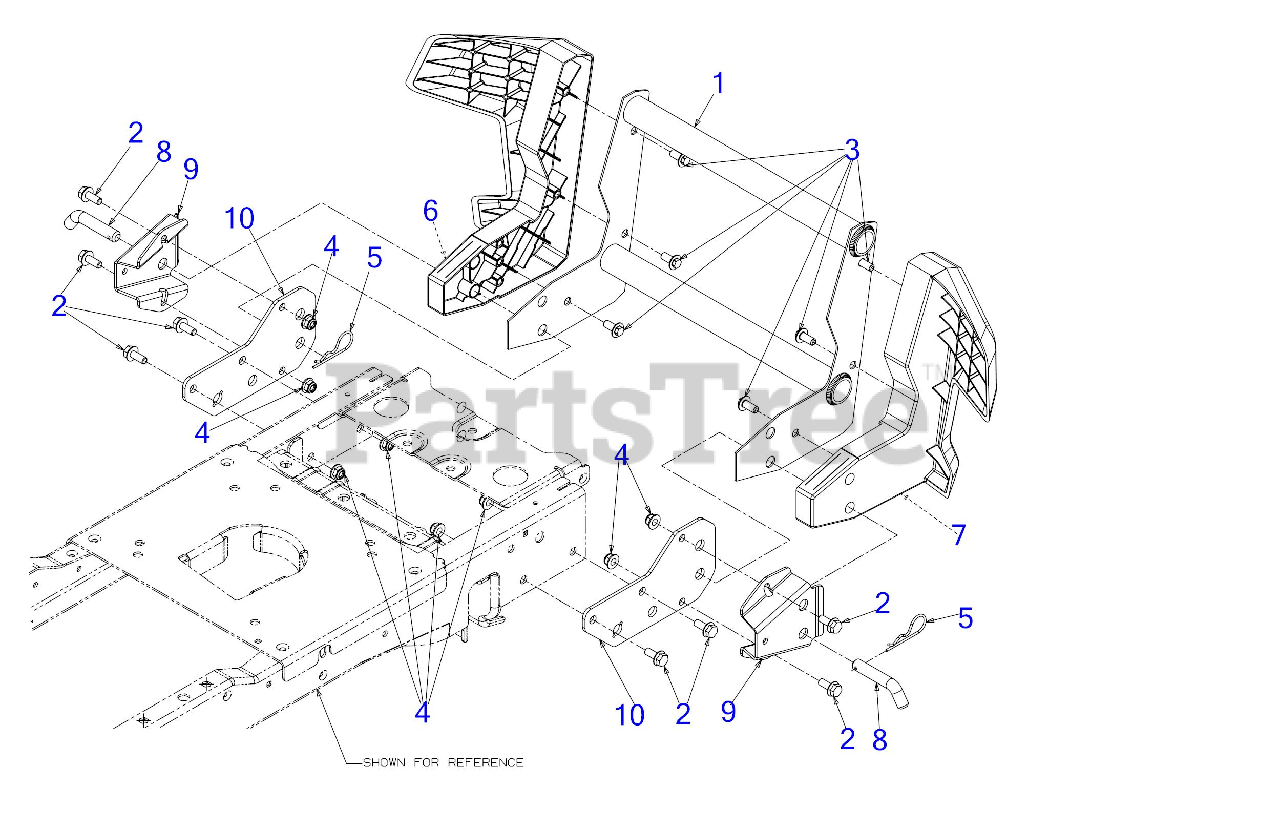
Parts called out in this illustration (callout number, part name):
2	SCREW 5/16-18
3	SCREW 5/16-14 x .750
4	FLANGE LOCK NUT 5/16-18
5	INTERNAL COTTER PIN
6	GUARD (LH)
7	GUARD (RH)
8	PIN .500 x 1.78
